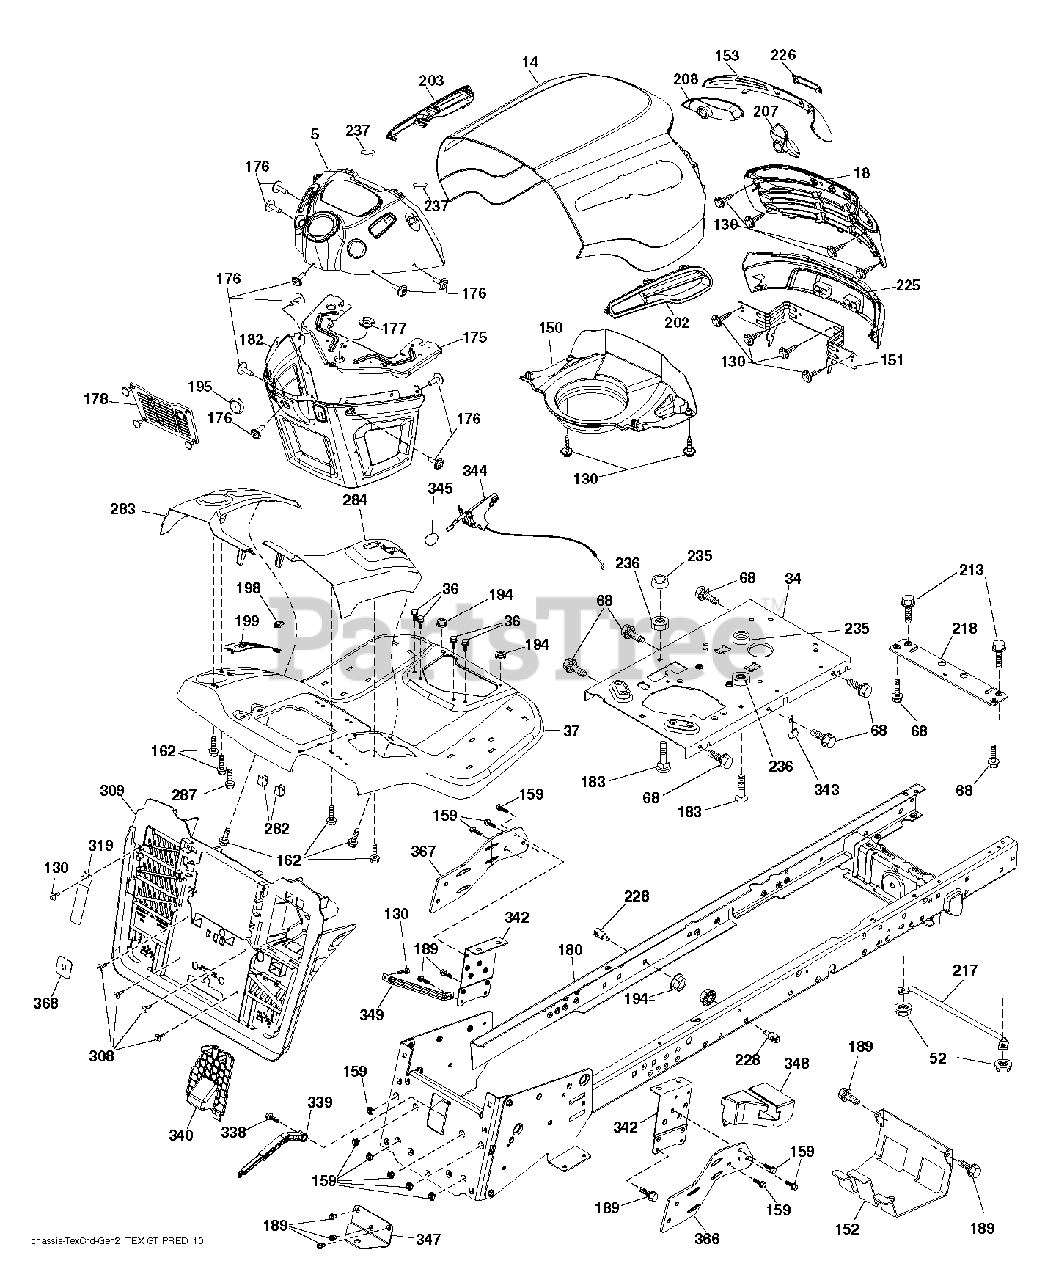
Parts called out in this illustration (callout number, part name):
36	SCREW 5/16"
52	LOCKNUT
130	SCREW.#10 X 0.750.BOS THREAD
152	SHIELD BROWNING
159	SCREW, 3/8-16X3/4
162	SCREW.HI-LO.CONSOLE
175	PLATE.CROSSMEMBER.HUSQ
176	SCREW.#10-24X5/8.RN.QU
177	BUSHING,STEERING
178	CARGO.ASM.NET.TXGT.W/C
183	BOLT.5/16-18X1-1/4 FULL THD
189	SCREW
194	NUT LOCK HEX FLANGE 5/16-18
195	PLUG.HOLE.DASH.LOWER.12V.BLK
198	INDICATOR.DECK.LIFT.RED
213	BOLT
217	ROD.PIVOT.HOOD
218	X-PIECE.HOOD.STOP.NON/
228	STUD.FASTNER.W/ANTI-ROTATE
235	SPACER FENDER
236	NUT.CENTERLOCK.5/16-
237	PLUG.MOUNT.CARGO.BLK
282	CLIP.RETAINER.CONSOLE.LT.HUSQ
308	BOLT, 5/16-18 X 1 3/4
